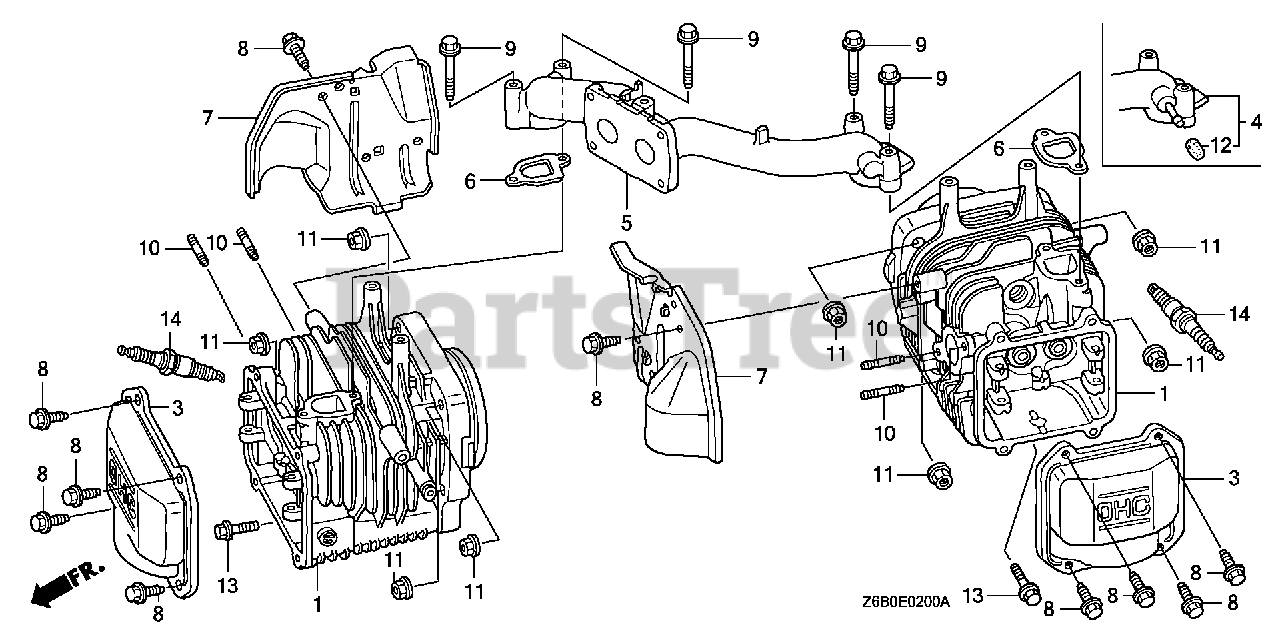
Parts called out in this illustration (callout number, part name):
3	COVER, HEAD
5	MANIFOLD, IN.
6	GASKET, IN. MANIFOLD
8	BOLT, FLANGE (6X12) (CT200)
9	BOLT, FLANGE (6X45)
10	BOLT, STUD (6X28) (CT200)
11	NUT, FLANGE (8MM)
13	BOLT, FLANGE (6X30)
14	SPARK PLUG (BPR4ES) (NGK)
14	SPARK PLUG (W14EPR-U) (DENSO)
14	SPARK PLUG (BPR5ES) (NGK)
14	SPARK PLUG (W16EPR-U) (DENSO)
